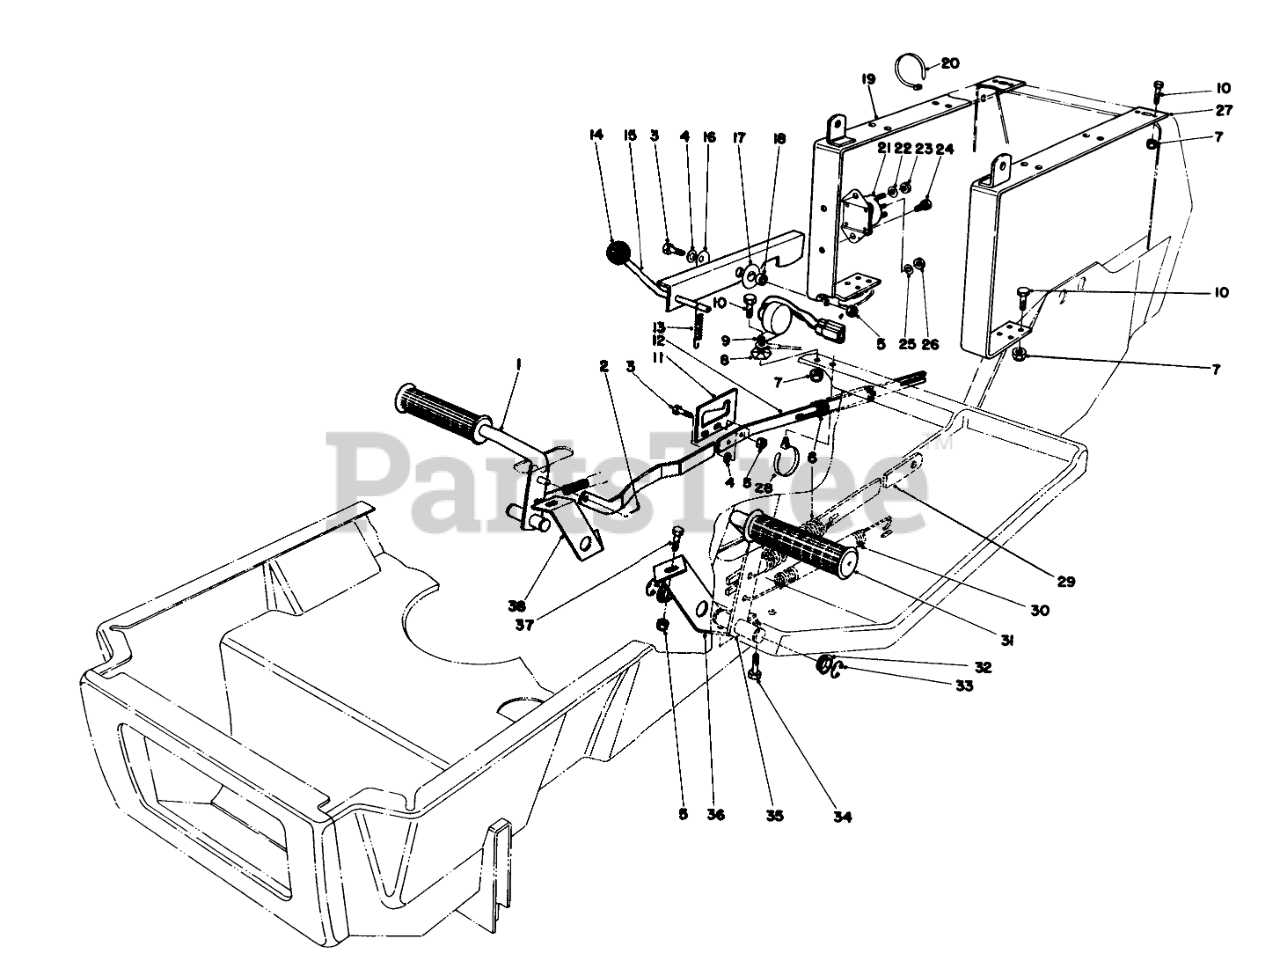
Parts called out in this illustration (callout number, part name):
1	BRAKE PEDAL WA BO
2	PIN-COTTER
3	Screw
4	WASHER-PLAIN
5	NUT-LOCK, NI
6	EXT SPRING O
7	NUT-LOCK, NI
8	Washer
9	Module Interlock
10	SCREW-HH
11	LATCH PLT-BRAKE ROD
12	LINK BRAKE ROD WAB
13	CONT ROD SPRING 0
14	Knob
15	PARKING BRAKE WA B
16	Belleville Washer
17	WASHER-PLASTIC
18	SPACER
19	RR BODY STRAP WA B
20	TIE-CABLE
21	SOLENOID
22	WASHER-LOCK
23	NUT-JAM, BRASS
24	SCREW
25	WASHER-LOCK
26	NUT-HEX
27	LH RR BODY STRAP WA B
28	TIE-MOUNT, PUSH
29	CLUTCH ROD LINK B
30	SPRING-EXTENSION
31	FOOT PAD
32	Nyliner
33	E-RING
34	SCREW-HWHTF
35	CLUTCH PEDAL WA BO
36	LH PEDAL SUPT B
37	SCREW-HH
38	RH PEDAL SUPT B
